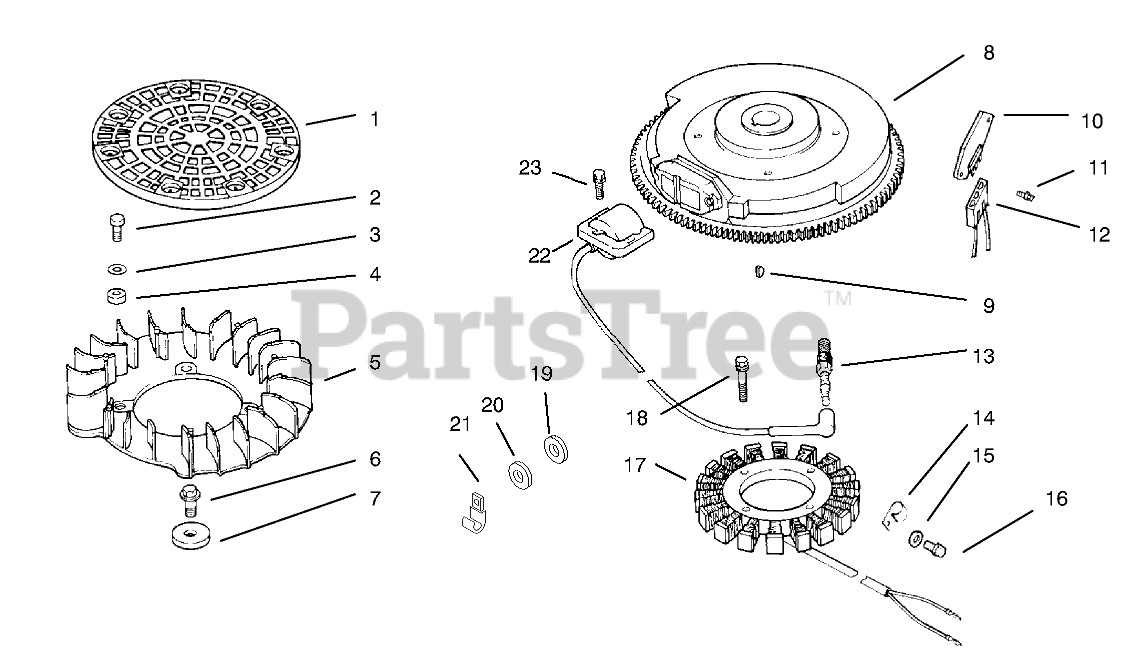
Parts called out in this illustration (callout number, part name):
1	Screen-Grass
2	Screw-Hex.
3	Washer
4	Spacer-Fan
5	Fan
6	Screw
7	Spacer
8	Flywheel
9	Key
10	Rectifier-Regulator
11	Screw
12	Connector
13	Plug-Spark
14	Clip
15	Washer
16	Screw
17	Stator-15 Amp
18	Screw
19	Washer
20	Washer
21	Clip
22	Module-Ignition
